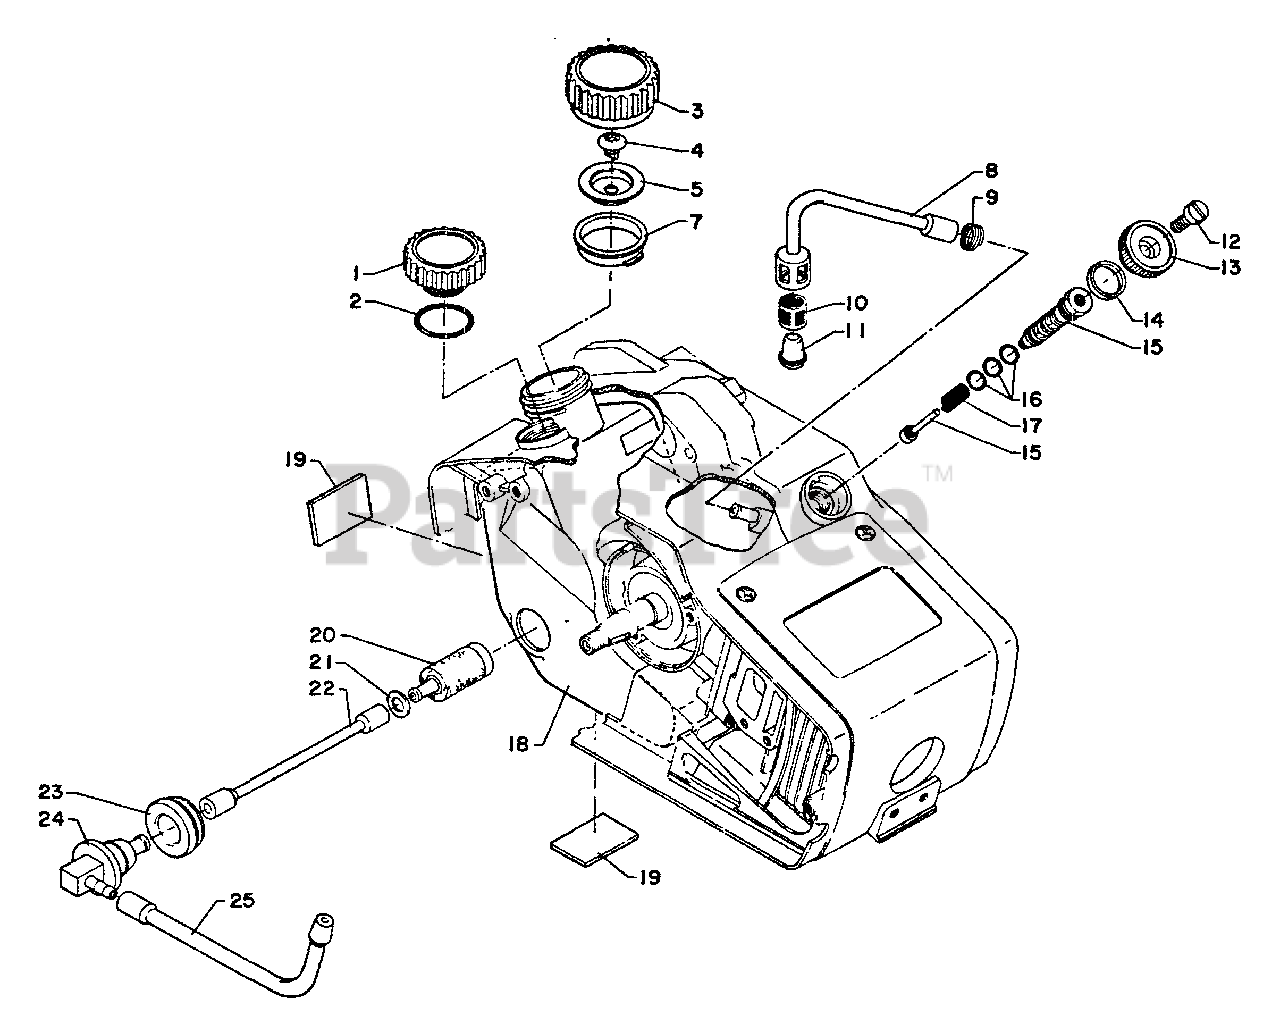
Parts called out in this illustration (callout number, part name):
1	CAP ASSY
2	O-RING - 16
3	CAP
5	HOLDER, VENT
7	GASKET
8	PIPE, OIL - INNER
10	FILTER, OIL
11	STRAINER WEIGHT
12	SCREW - 5X14
13	DIAL, AUTO-OILER
14	FLAT SPRING
15	PUMP KIT
16	O-RING - 5
18	TANK, FUEL
19	CUSHION - LOWER
20	FILTER, FUEL
21	WASHER - 6
22	PIPE - INNER
23	GROMMET
24	CONNECTOR, PIPE
25	PIPE, FUEL - OUTER
